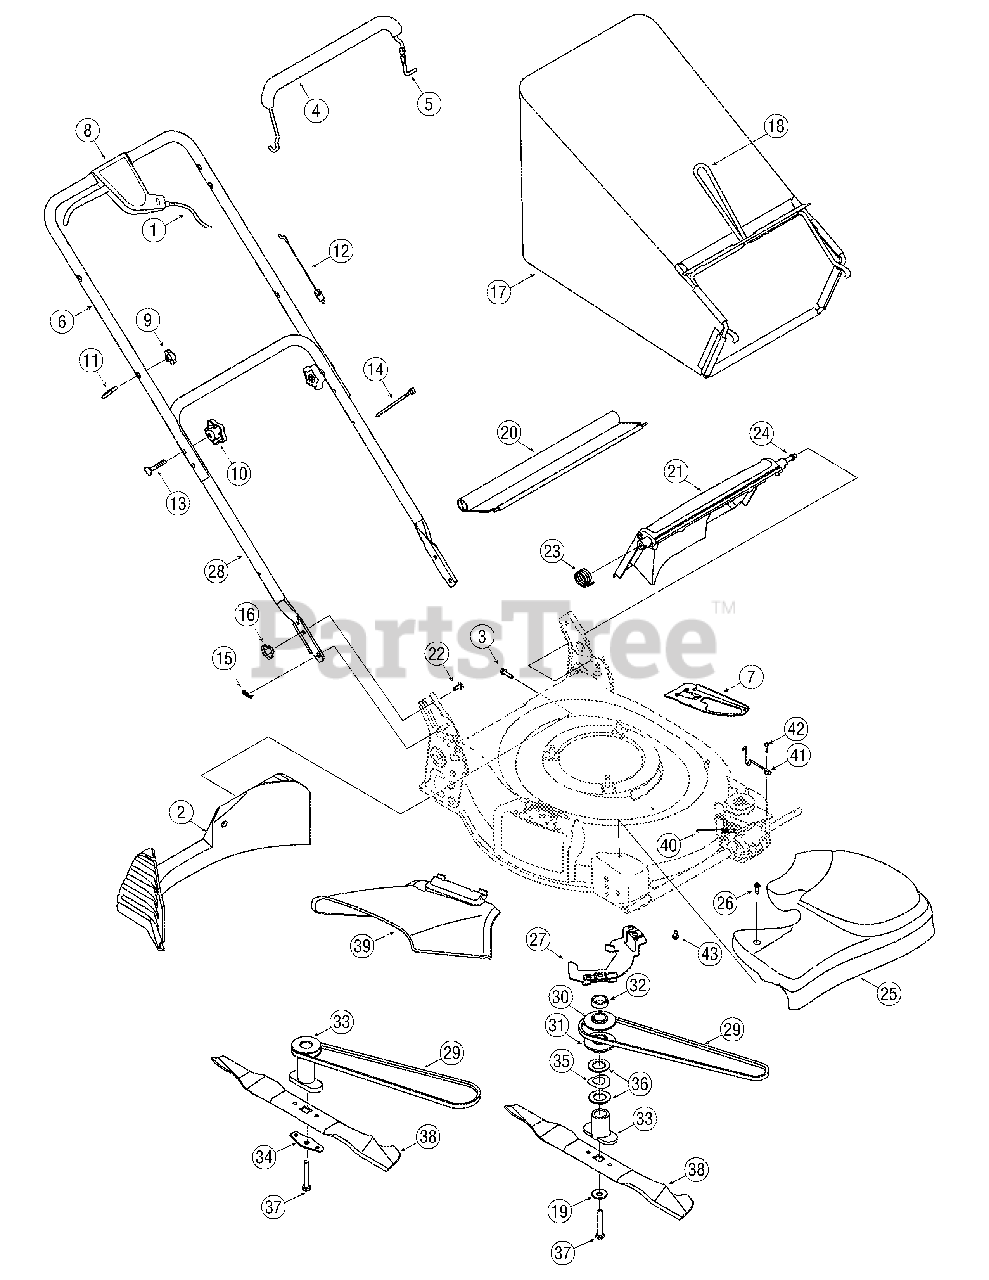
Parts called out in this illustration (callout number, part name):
1	Variable Speed Cable
2	Rear Baffle 21" Rd.
3	Screw 1/4-15 x 1.000
4	Deluxe Bail Cover
8	Control Lever Assembly
9	Handle Knob
10	Star Knob
12	Control Cable - 37.25"
12	Control Cable - 37.75"
12	Control Cable - 40"
12	Control Cable - 40.75"
13	Carriage Bolt 5/16-18 x 2.0
14	Cable Tie
15	Cotter Pin
16	Wing Nut
17	Grassbag Assembly
19	Wash., Bell, .396 x 1.140 x .095
20	Rear Trailing Shield
21	Rear Discharge Door
22	Carriage Bolt 1/4-20
23	Torsion Spring - RH
25	Transmission Cover (Black)
26	Shoulder Screw # 12 -24
29	V-Belt
30	Upper Pulley Half 25mm x 2.62
31	Lower Pulley Half 25mm x 2.62
32	Slv Spacer 25mm x 1.375 x .62
33	Blade Adapter
33	One Piece Blade Adapter
34	Blade Bell Support
35	Space Washer
36	Flat Washer
37	Hex Screw 3/8-24 x 2.50
38	21" Mulching Blade
39	Side Discharge Chute
40	Extension Spring
41	Belt Keeper Wire
42	Torx Screw
43	Scr., 1/4-14 x.625
